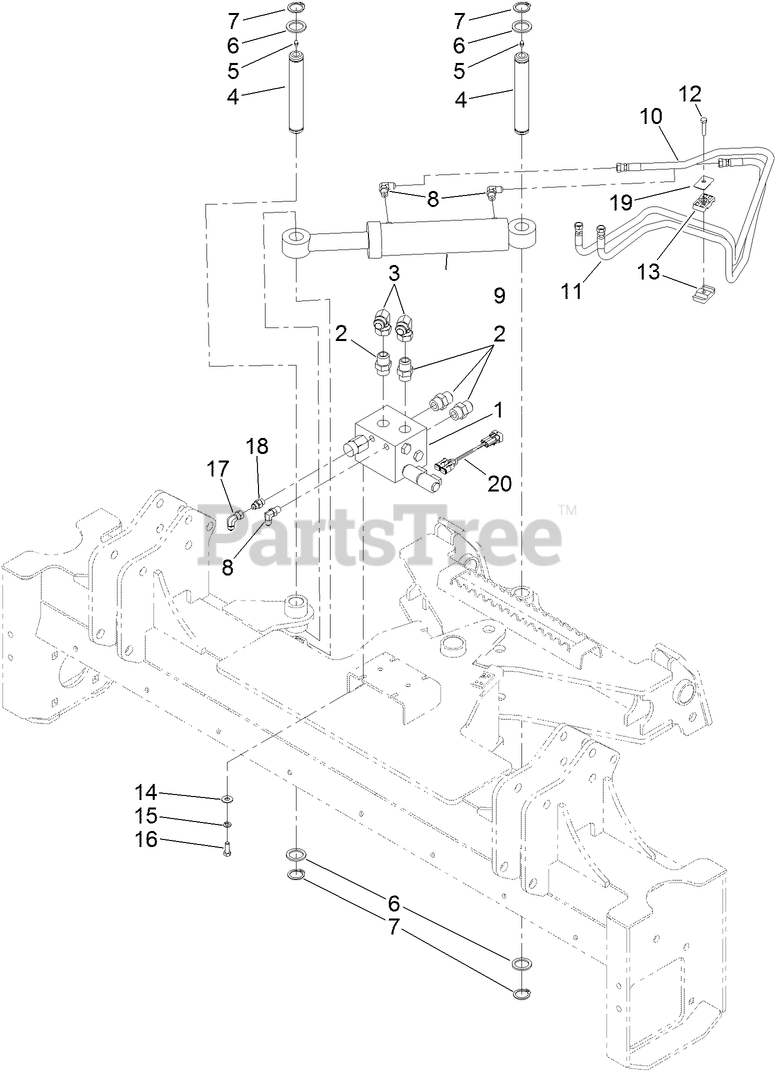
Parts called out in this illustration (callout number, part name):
1	HYDRAULIC MANIFOLD ASM
2	FITTING-ADAPTER
3	FITTING-ELBOW, 90
4	PIN-PIVOT
5	FITTING-ZERK
6	WASHER
7	RING-RETAINING, EXTERNAL
8	FITTING-ELBOW
9	HYDRAULIC CYLINDER ASM
10	HOSE-HYD
11	HOSE-HYD
12	SCREW-HH
13	CLAMP-TUBE
14	WASHER-FLAT
15	WASHER-LOCK
16	SCREW-HH
17	ELBOW-SWIVEL, 90 DEG
18	FITTING,STRAIGHT,6-MORB X 6-M37JIC
19	COVERPLATE
20	HARNESS-WIRE
